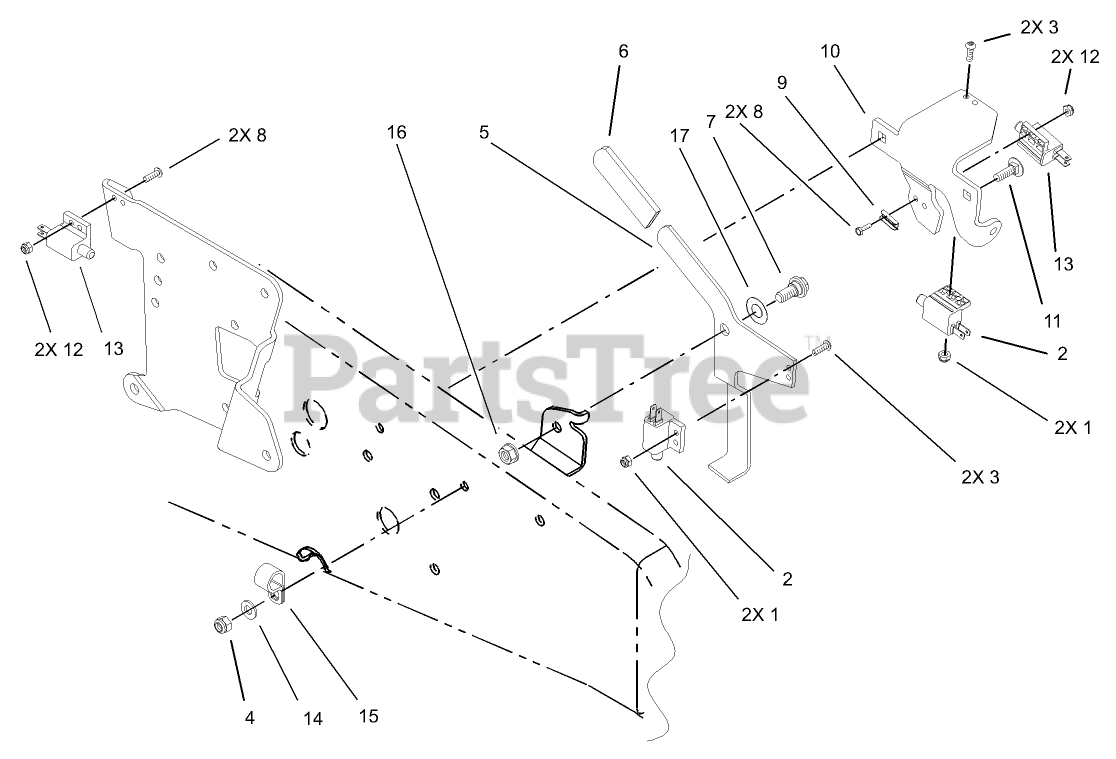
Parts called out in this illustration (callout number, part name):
1	NUT-LOCK, NI
3	SCREW-HSH
4	NUT-LOCK, NI
5	LATCH-BRAKE, PARKING
7	BOLT-SHOULDER
8	SCREW
9	RETAINER-SCREW
10	BRACKET-SWITCH
11	SCREW-CARR
12	NUT-LOCK
13	SWITCH-POLE, SINGLE
14	WASHER-PLAIN
15	CLAMP - R
16	NUT-HEX
17	WASHER
